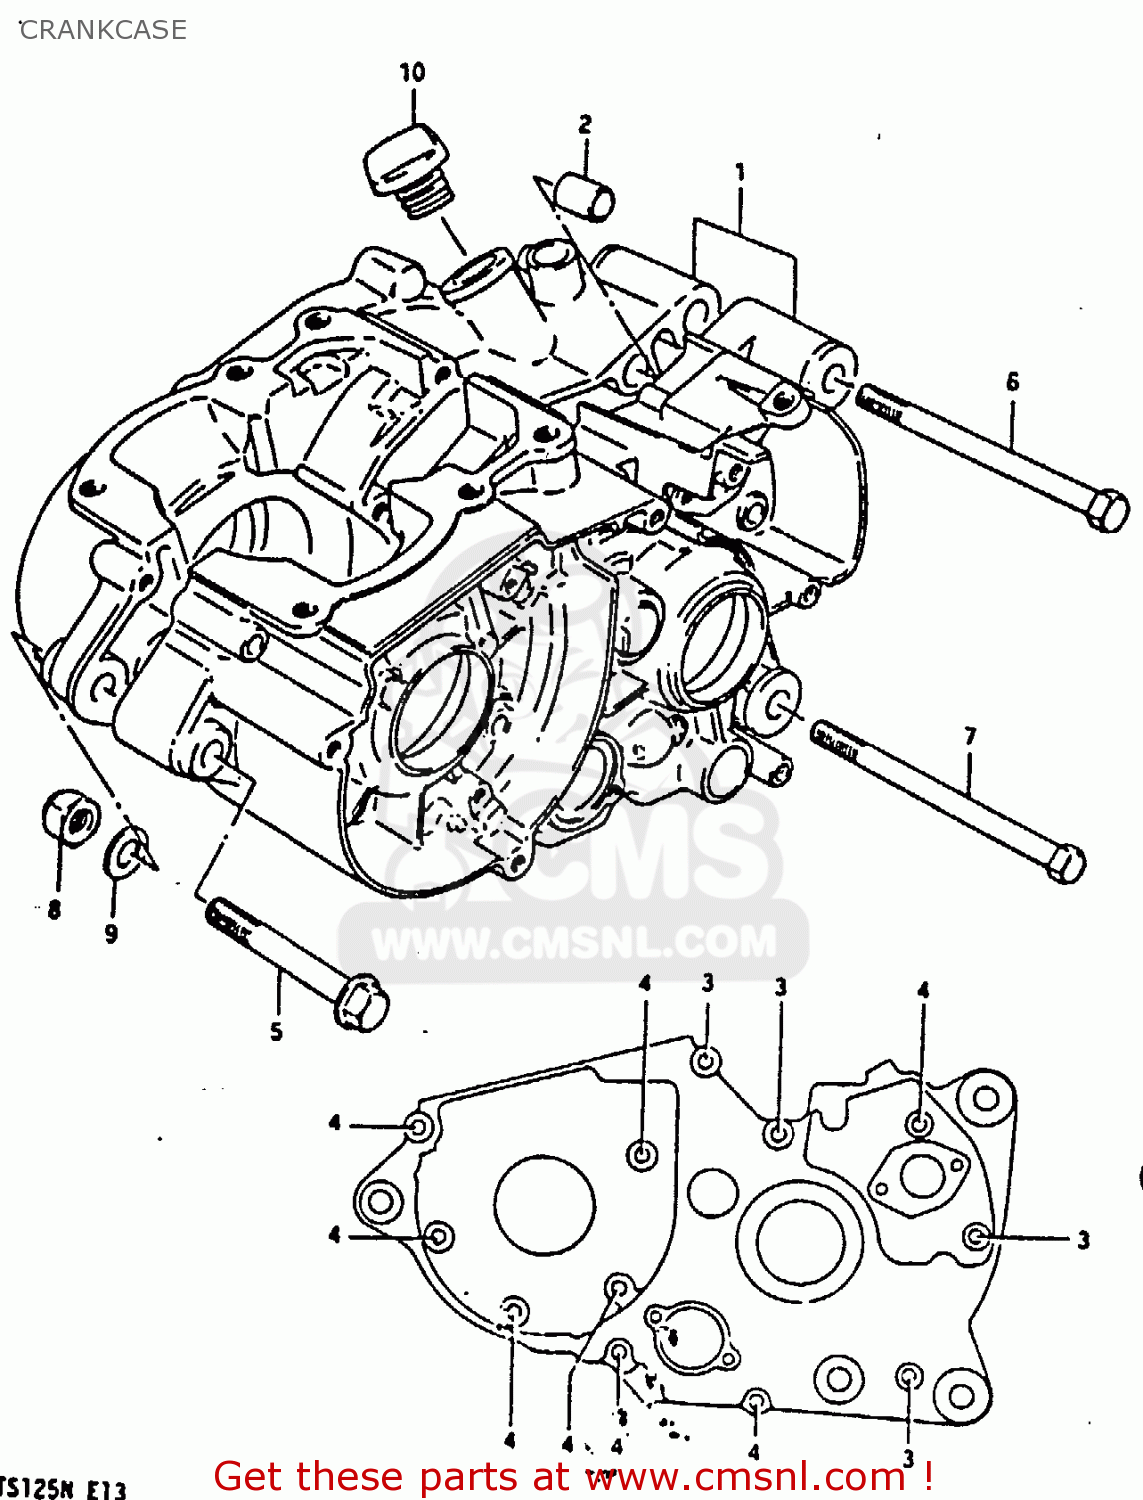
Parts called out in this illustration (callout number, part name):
1	CRANKCASE ASSEMBLY
2	PIN
3	SCREW
4	SCREW 6X60
5	BOLT (10X75)
6	BOLT(10X110)
7	BOLT
8	NUT
9	WASHER
10	PLUG
